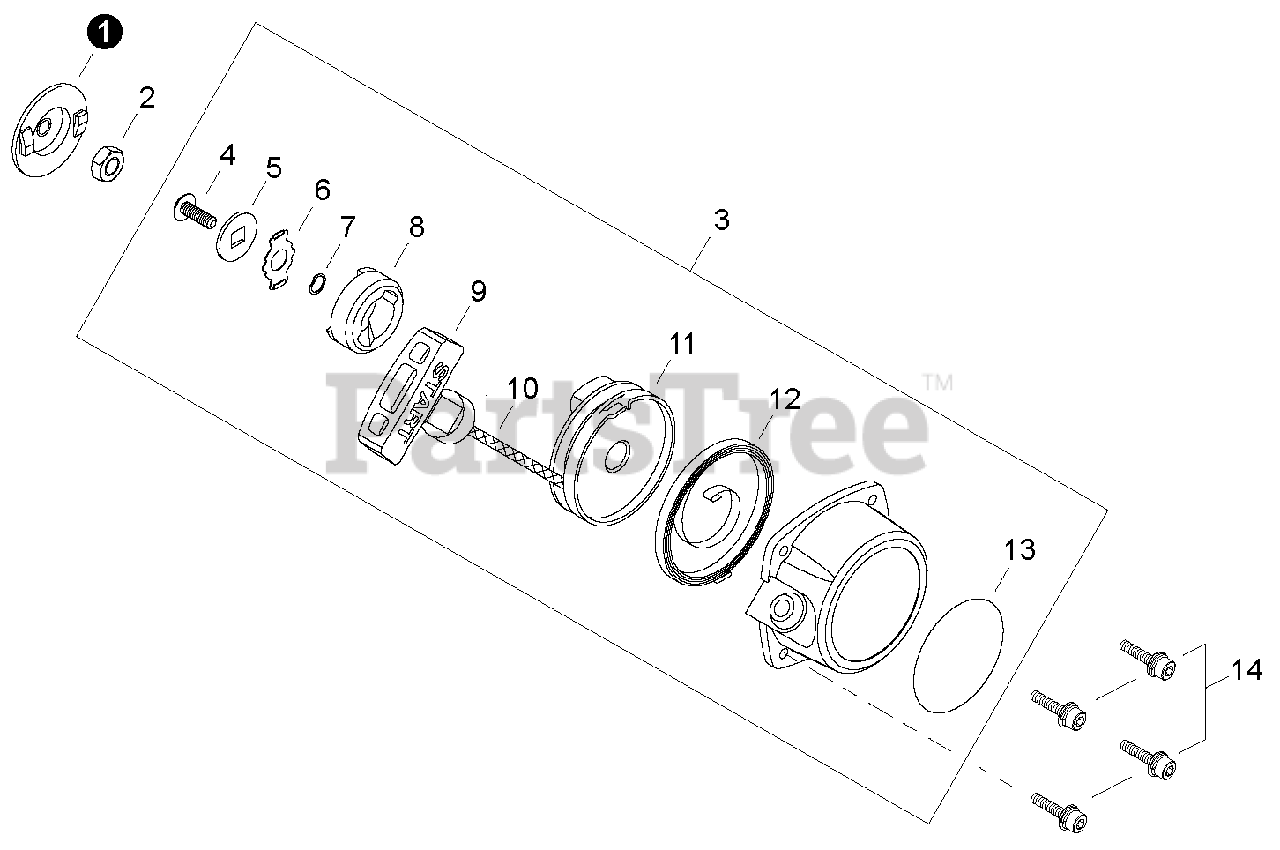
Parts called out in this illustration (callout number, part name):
1	PAWL, STARTER
2	NUT - 8
3	STARTER ASSY
4	SCREW - 5
5	WASHER - 5
6	RETAINER
7	WASHER - SPRING
8	CATCHER, PAWL
9	GRIP, STARTER
10	ROPE, STARTER
11	REEL, ROPE
12	SPRING, REWIND
13	LABEL - TRADE
14	SCREW - 4X12
